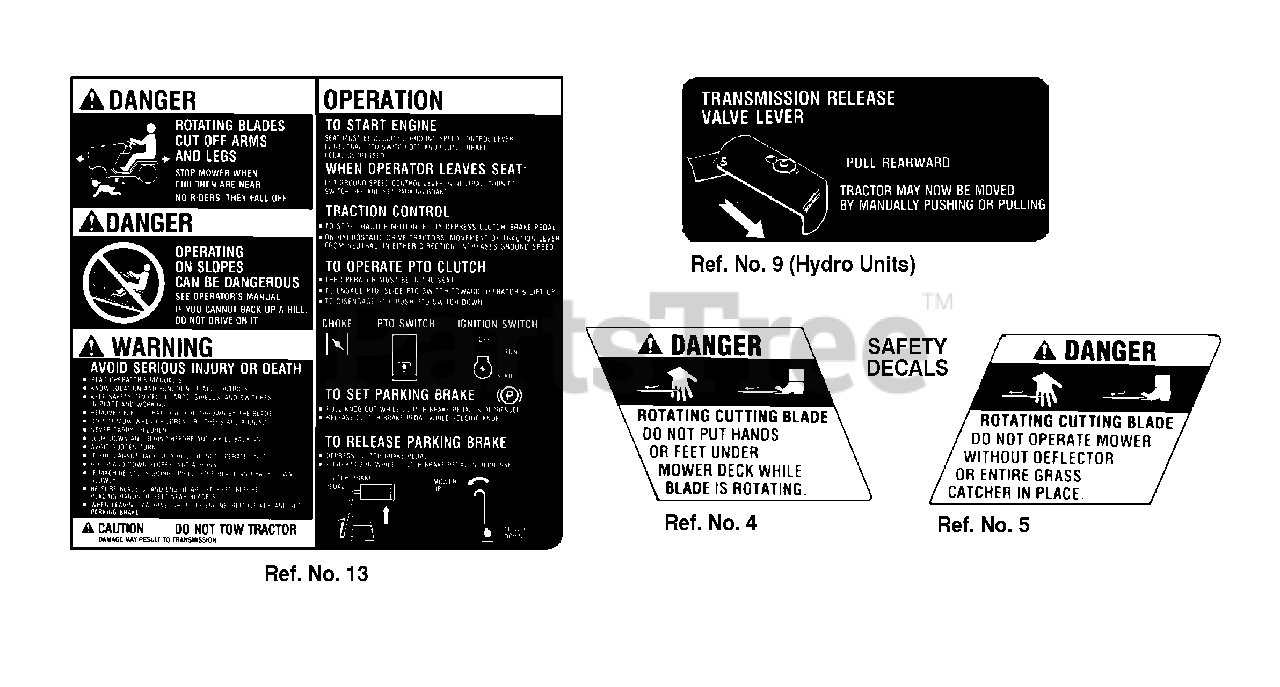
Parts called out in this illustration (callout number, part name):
4	DECAL, Danger (Hand under deck)
5	DECAL, Danger (Chute in place)
9	DECAL, Release Valve
13	DECAL, Operating Instructions
